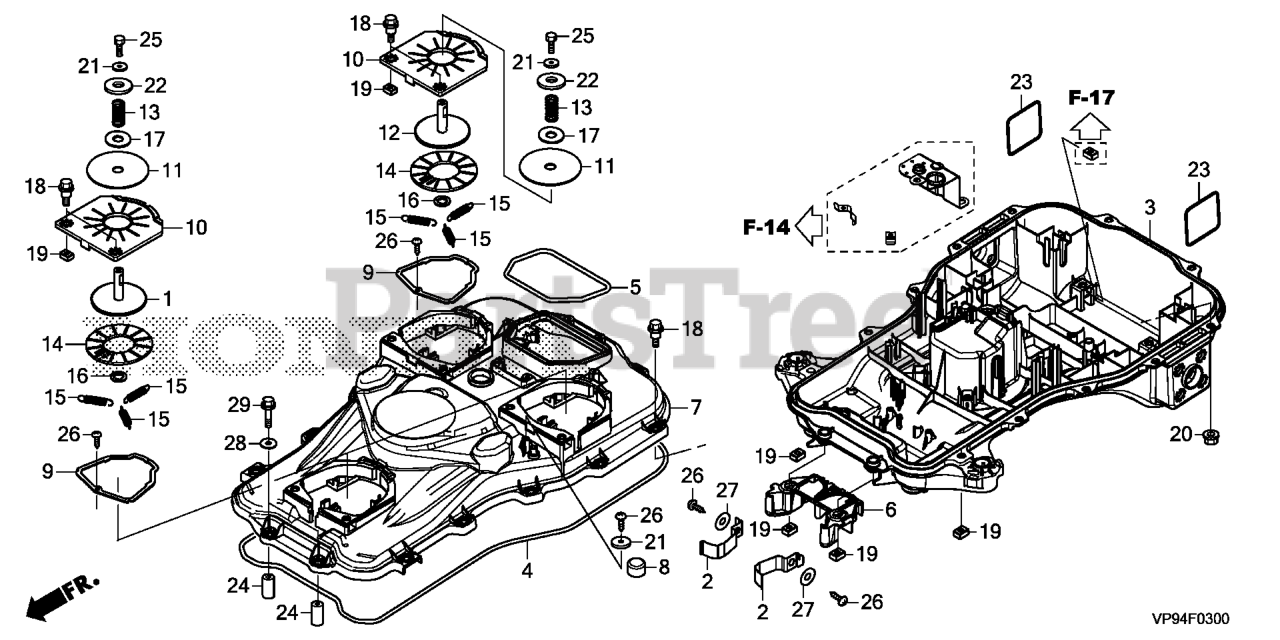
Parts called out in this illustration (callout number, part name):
1	MAGNET, OBSTRUCTION
2	SOCKET, L. CHARGE
3	FRAME (LOWER)
4	SEAL A, FRAME
5	SEAL B, FRAME
6	COVER, SOCKET
7	FRAME (UPPER)
8	CAP, BREATHER
9	PLATE, SPRING
10	PLATE, MOUNT
11	WASHER, LIFT
12	SHAFT B, MOUNT
13	SPRING, COVER MAIN
14	WASHER, MOUNT
15	SPRING, MOUNT
16	WASHER, SPRING
17	RUBBER, MOUNT
18	BOLT, FLANGE (6MM)
19	NUT, SPECIAL (6MM)
20	NUT, FLANGE (6MM)
21	WASHER, PLAIN (5MM)
22	WASHER, PLAIN (12MM)
23	O-RING, MOTOR MOUNT
24	COLLAR, CARRY GRIP
25	BOLT, HEX. (5X12)
26	SCREW, TAPPING (4X12)
27	WASHER, PLAIN (5MM)
28	WASHER, PLAIN (6MM)
29	BOLT, FLANGE (6X35)
